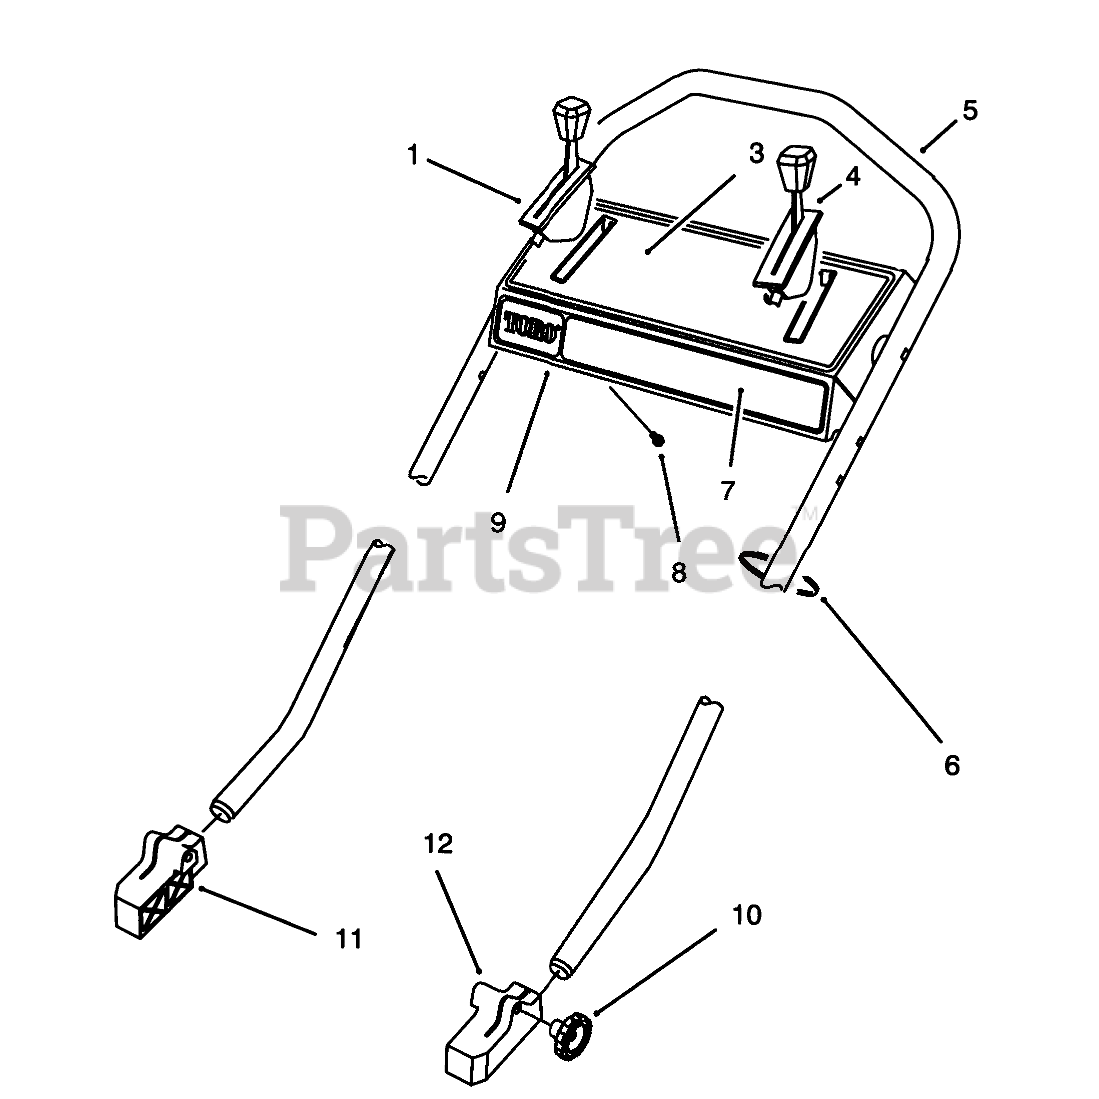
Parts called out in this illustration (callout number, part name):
1	CONTROL-SPEED, GROUND
3	DECAL - INSTRUCTION
4	CONTROL - THROTTLE
5	HANDLE - 53CM (DIPPED)
6	TIE-CABLE
7	DECAL - PANEL 2 CYCLE
8	SCREW-TAP
9	Control Panel Assembly (Incl. Ref. #3, & 7)
11	MOUNT-HANDLE, RH
12	MOUNT-HANDLE, LH
